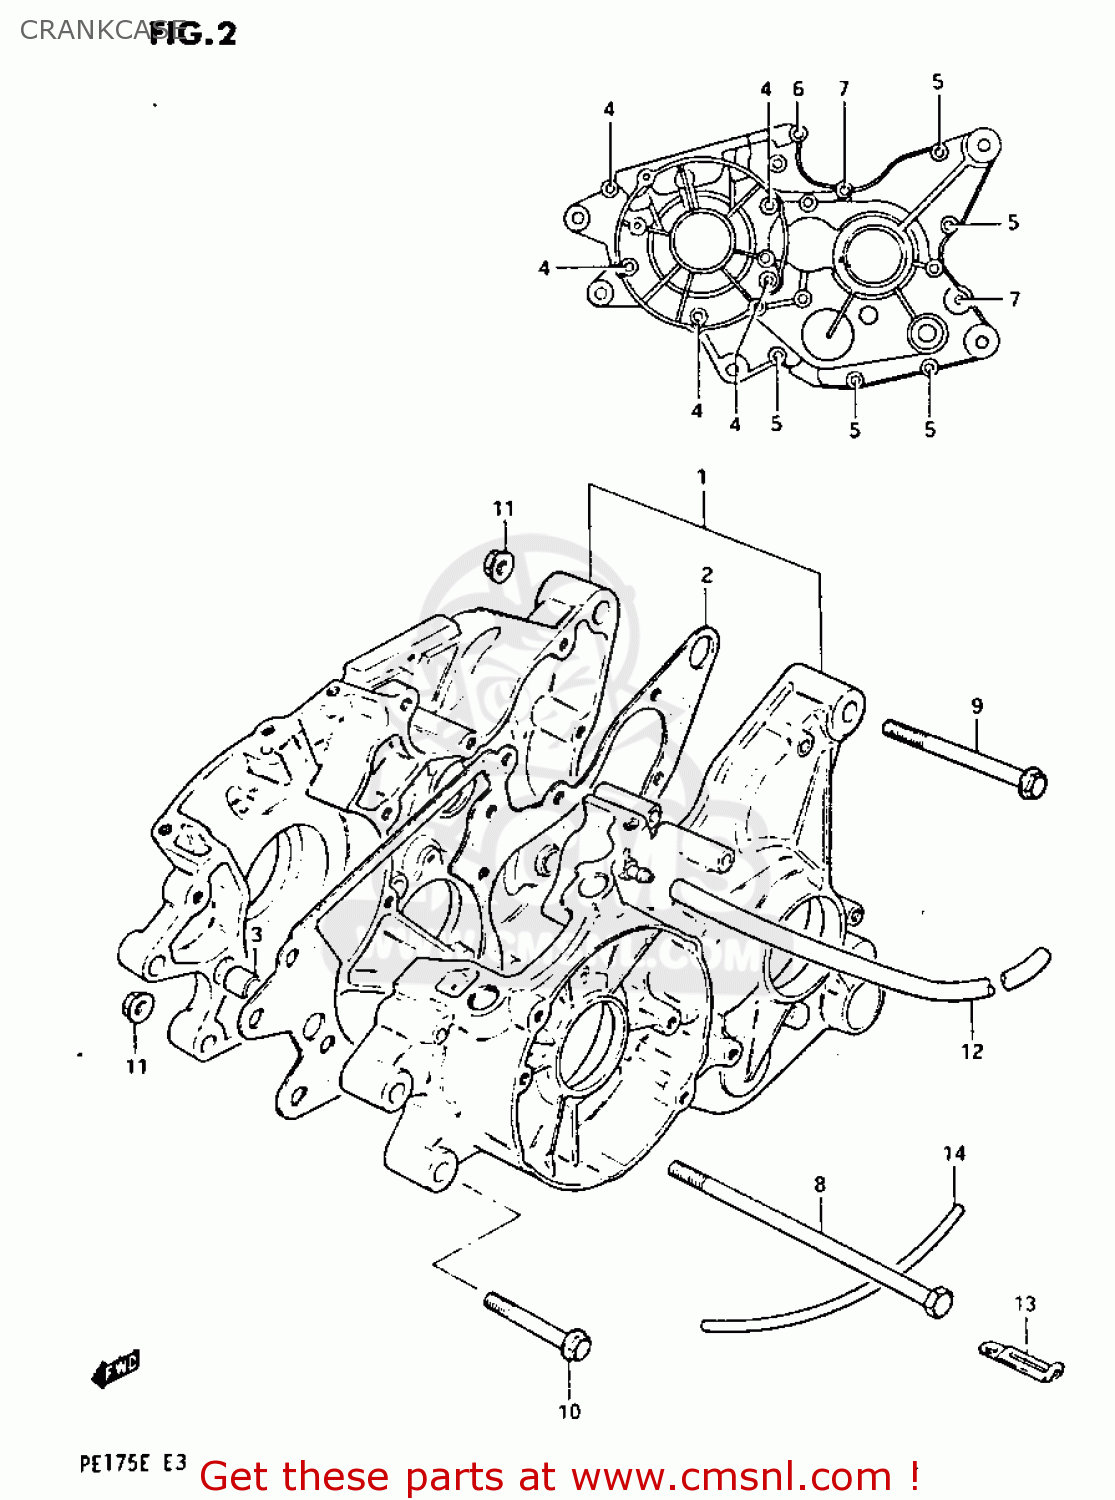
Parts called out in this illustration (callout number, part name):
1	CRANKCASE SET
2	GASKET,CRANKCASE
3	PIN
4	SCREW
5	SCREW
6	SCREW
7	SCREW 6X60
8	BOLT 8X175
9	BOLT (8X95)
10	BOLT 8X65
11	NUT
12	HOSE,FUEL
13	CLAMP
14	HOSE(4X7X600)
